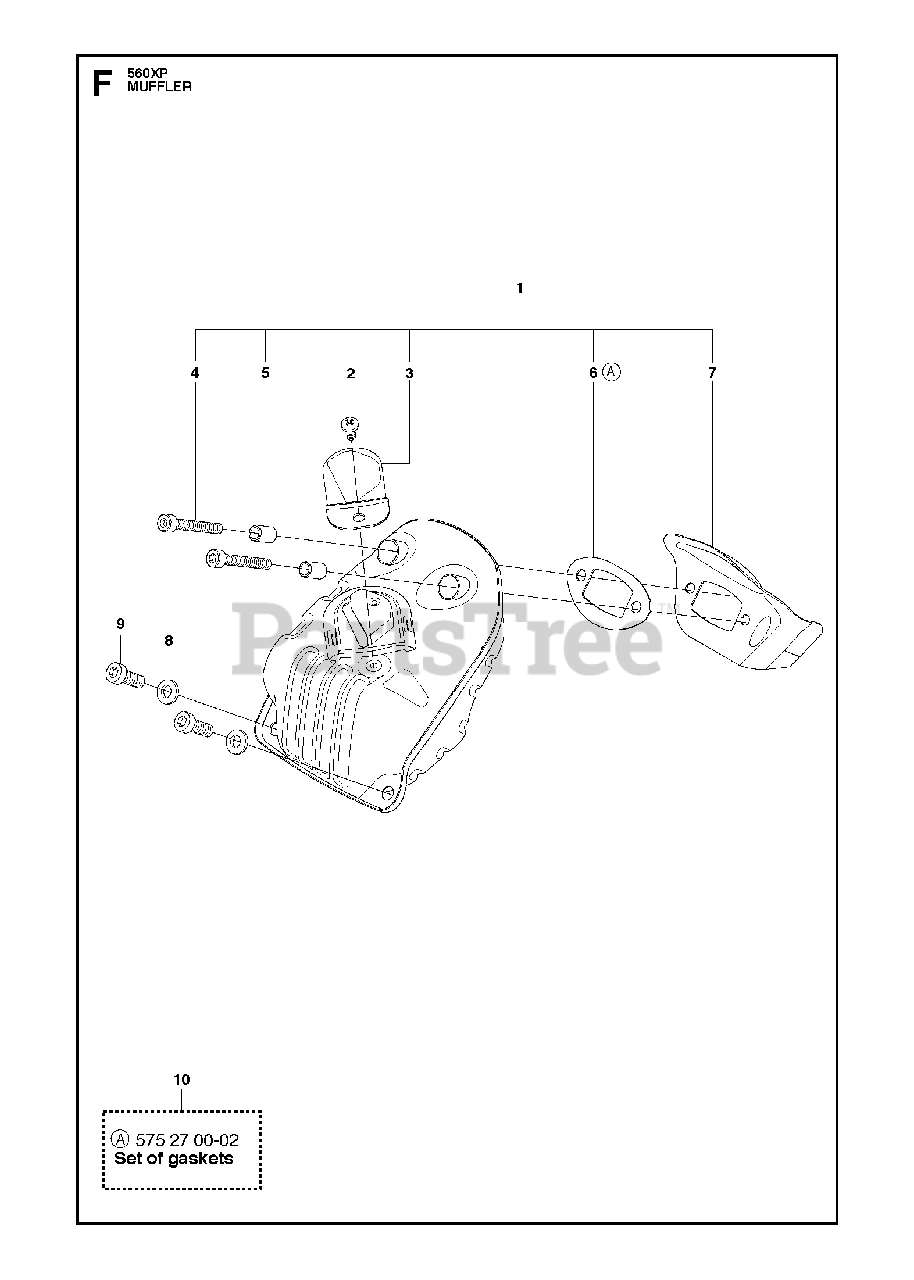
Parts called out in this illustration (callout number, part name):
1	MUFFLER KIT
2	SCREW
3	SPARK ARRESTER
4	SCREW
5	SLEEVE MUFFLER
6	GASKET MUFFLER
7	HEAT DEFLECTOR
10	GASKET KIT
